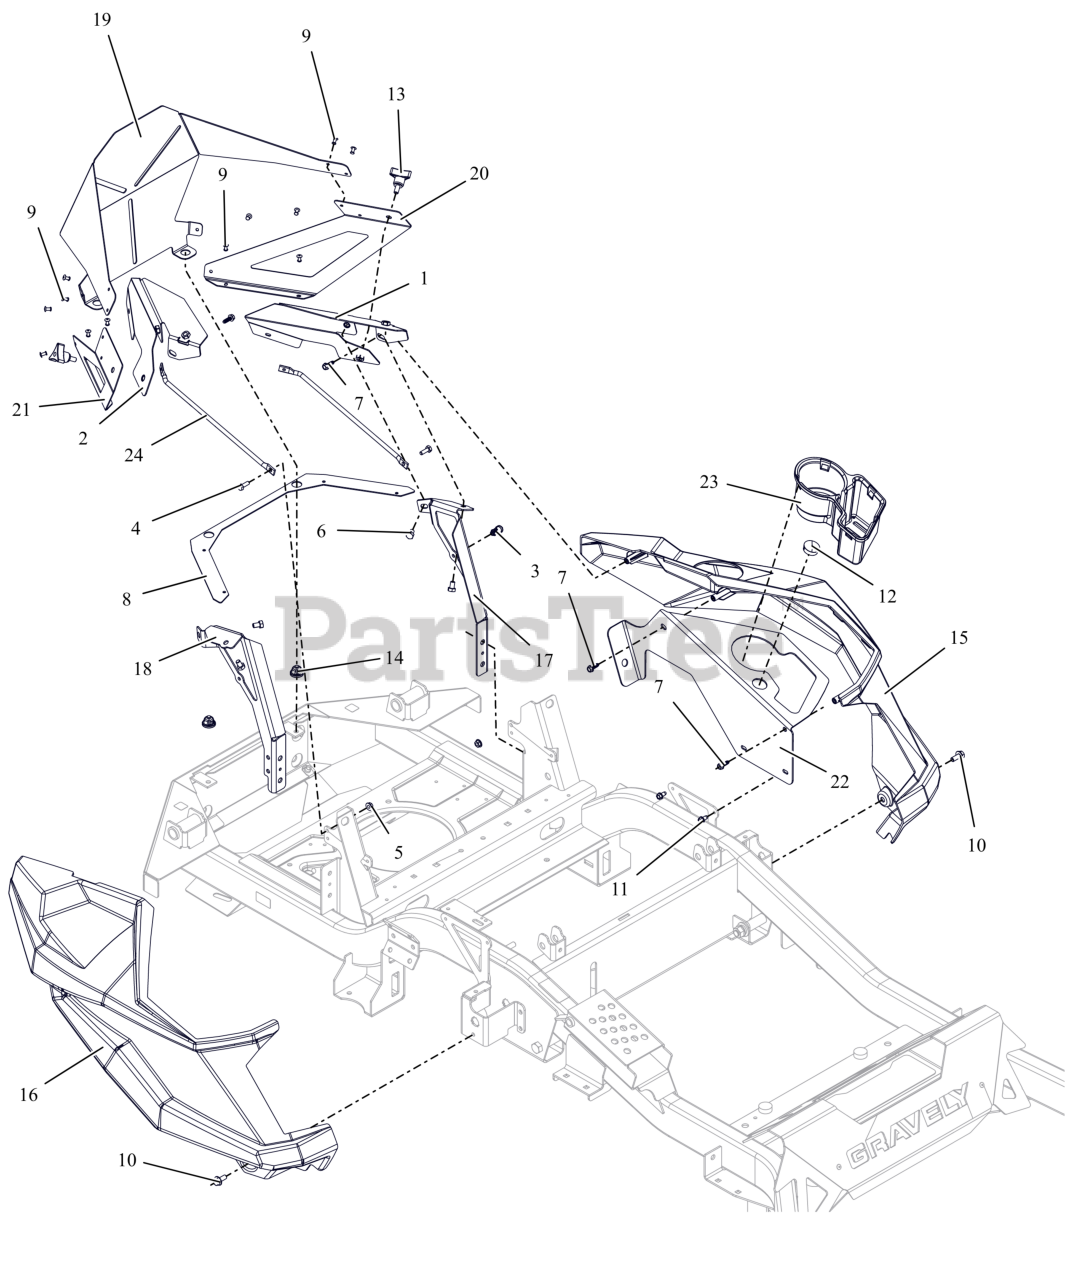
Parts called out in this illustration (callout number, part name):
1	PANEL, LH (RED)
2	PANEL, RH (RED)
3	CLIP, CABLE GUIDE
4	BLT, HEX .25-20X.75 G5 ZCC
5	NUT-LK-CTR-FLG .25-20 ZC120
6	BLT, HEX .31-18X.50 GR5 ZCC
7	SCR, PLASTITE-HWH 0.25 X 0.75 ZC120
8	STIFFENER, BACK WRAP (RED)
9	RIVET, #66 STEEL POP PD BLACK
10	BLT, SERHFWH 0.312-18X0.75 GR5 ZCC
11	SCR-TAP .25-20X.50 HWH ZCC
12	PLUG, HOLE 1.125 DOMED
13	KNOB,WING STUD 5/16-18 X .75
14	GROMMET, 10MM BOLLHOFF
15	FENDER, LH
16	FENDER, RH
17	BRKT, LH FENDER MTG (RED)
18	BRKT, RH FENDER MTG (RED)
19	WRAP, REAR (BLACK)
20	WRAP, REAR - LH (RED)
21	WRAP, REAR - RH (RED)
22	PANEL, HD CUPHOLDER (RED)
23	HOLDER, CUP
24	ROD, STIFFENER
